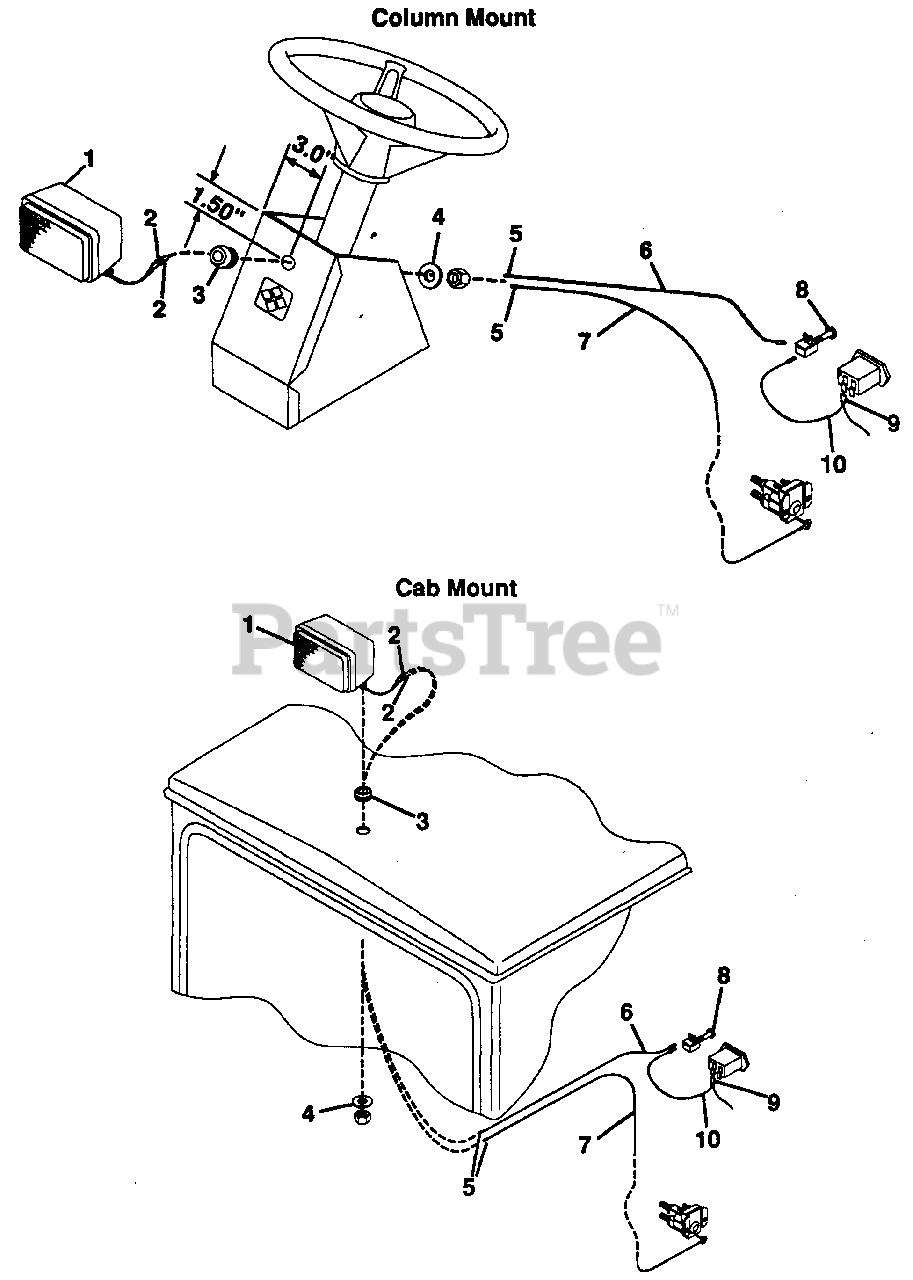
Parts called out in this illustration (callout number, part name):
1	Headlamp, 3x5 Halogen
2	Terminal, Male
3	Grommet
4	Washer, Flat .531x1.000x.063
5	Terminal, Female
6	Wire, Headlight
7	Wire, Ground
8	Switch, Light
9	Terminal, Female 2-Wire
12	Wire, Headlight
